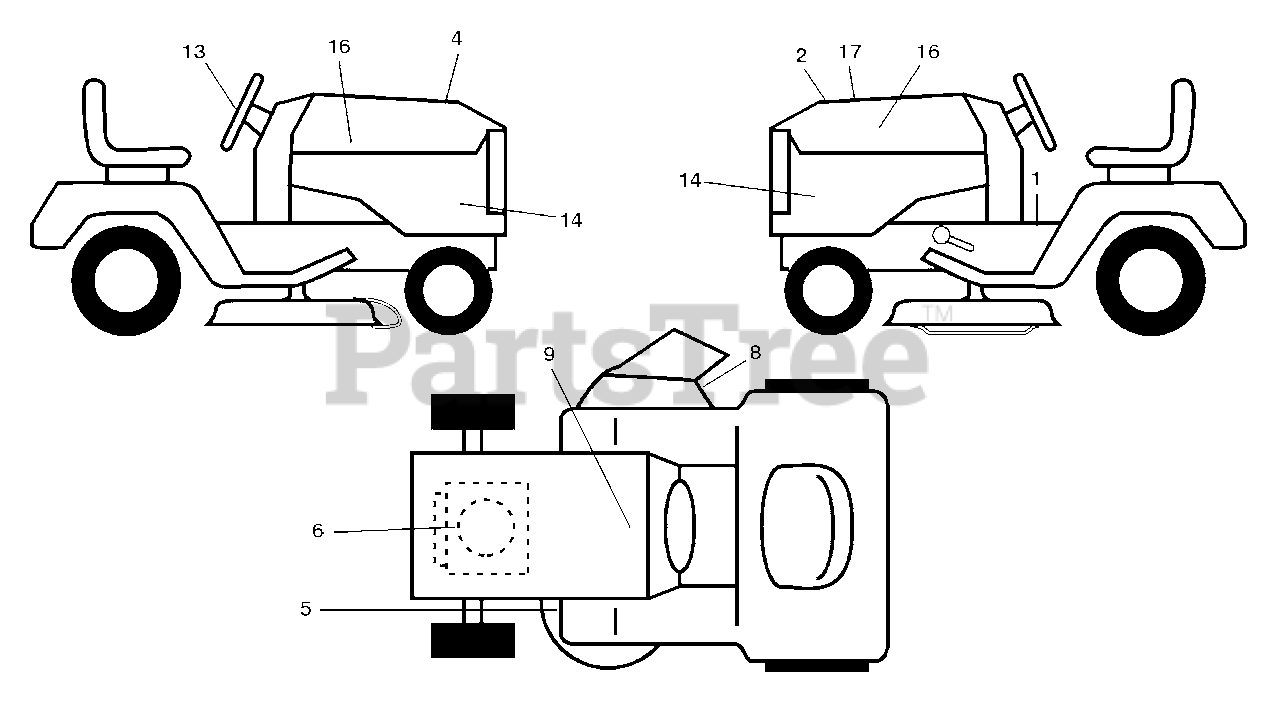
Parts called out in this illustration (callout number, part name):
1	Decal, Operator's
2	Decal, Hood Insert
4	Decal Hood Cust Resp.
5	Decal, Mower Sch.
6	Decal, Eng. HP
8	Decal, Warning
9	Decal, Battery Dnge/Poi
13	Decal, Steering Whl
14	Decal, Panel Side
16	Decal, Hood Logo
17	Decal, Replacement
